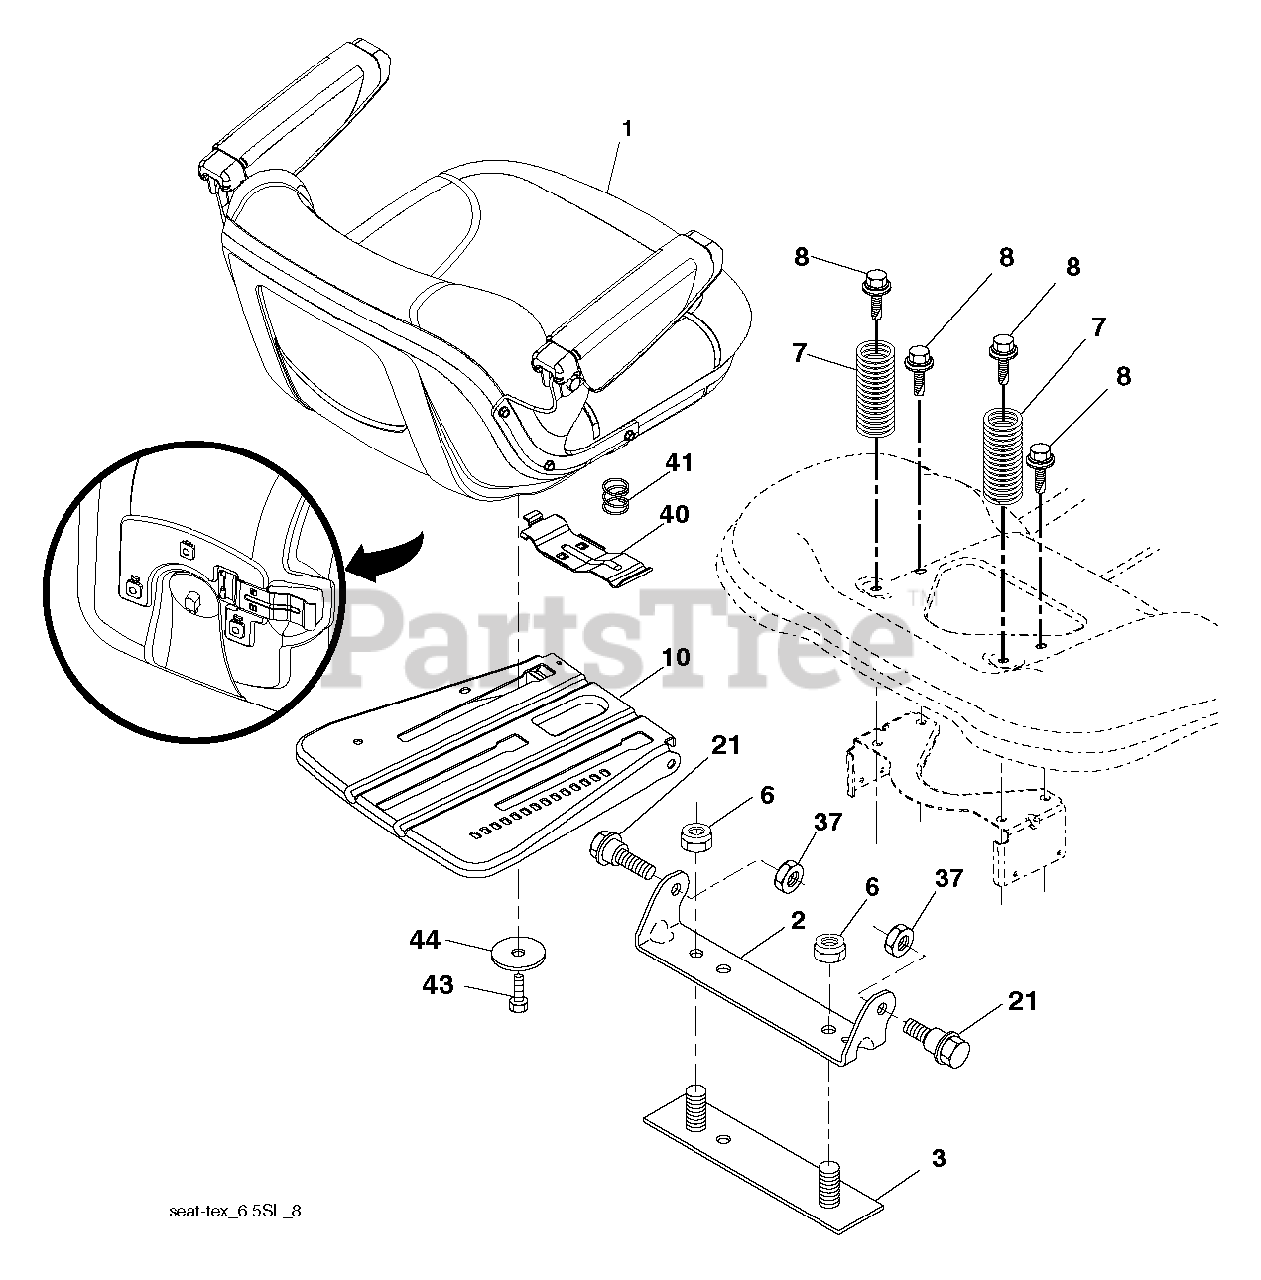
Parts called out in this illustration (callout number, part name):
1	SEAT.TH154.GREY.HUS.ARMREST
2	BRKT.PIVOT.FENDER
3	STRAP
6	NUT
7	SPRING COMPRESSION
8	BOLT, 5/16-18 X 1 3/4
10	PAN.ASM.SEAT.3PT
21	BOLT.SHOULDER.5/16-18
37	NUT.71038.31-18.HEX.NYLOCK
40	HANDLE.SLIDE.SEAT.TEX.GREY
41	SPRING.LATCH.SEAT.TEX
44	WASHER 13/32 X 2-3/8 X 12GA
